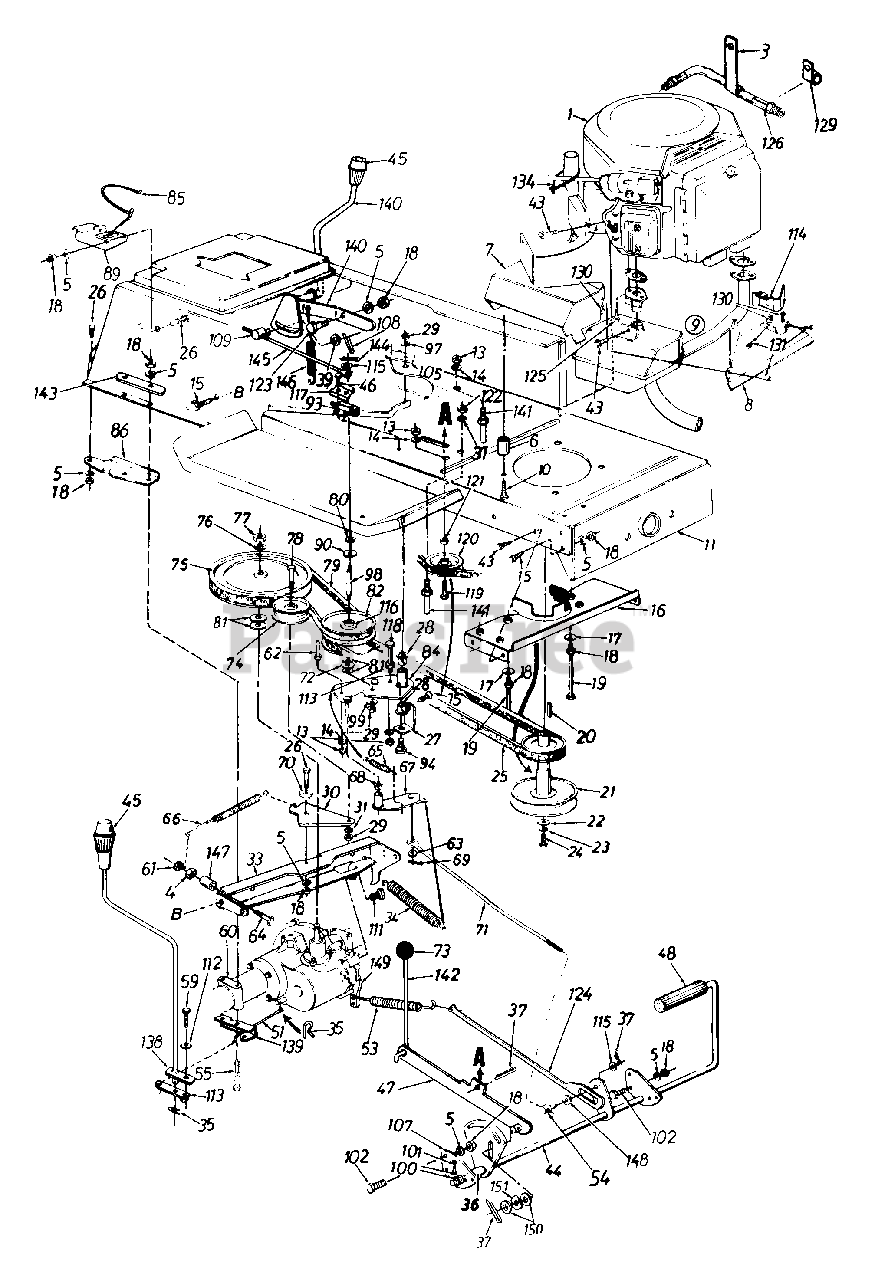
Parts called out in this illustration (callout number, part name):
1	Engine
4	Hex Nut 5/16-24 Thd.
5	L-Wash. 5/16" I.D.
6	Spacer 1.25" Lg.
7	Muffler Heat Shield
8	Front Heat Shield
9	Muffler Ass'y. Comp.
10	Hex L-Wash. Tap Scr. 3/8-16 Thd.
11	Lower Frame Ass'y.
13	Hex Nut 1/4-20 Thd.
14	L-Wash. 1/4" I.D.
15	Hex Wash. TT-Tap Scr. 5/16-18 x .62" Lg.
16	Belt Guard Brkt. Ass'y.
17	Bell-Wash. .345" I.D. x .88"
18	Hex Nut 5/16-18 Thd.
19	Hex Bolt 5/16-18 x 4.0"
20	Sq. Key 1/4" x 1/4" x 2.00"
21	Engine Pulley
22	Fl-Wash. 7/16" I.D. x 1.25"
23	L-Wash. 7/16" I.D.
24	Hex Bolt 7/16-20 x 1.50" Lg.
25	Variable-Speed Belt
26	Hex Bolt 5/16-18 x .75" Lg.
27	Bearing Shaft Bracket Ass'y.
28	Flanged Nyliner Brg. .63" I.D. x .6" Lg.
29	Hex Nut 3/8-24 Thd.
30	Idler Bracket
31	L-Wash. 3/8" I.D.
33	Transaxle Support Brkt.
34	Ext. Spring .94" O.D. x 7.58"
35	Inter. Cotter Pin
36	Spacer .63" I.D.
37	Cotter Pin 1/8" Dia. x 1.0" Lg.
39	FL-Wash. .51" I.D. x .75"
43	Hex Wash. Hd. S-Tap Scr. 1/4-20 x .50" Lg.
44	Clutch/Brake Pedal Ass'y.
46	Truss Mach. B-Tap Scr. #10 x .5" Lg.
47	Parking Brake Lockout Brkt. Ass'y.
48	Foot Pad
51	Shift Lever Rod
53	Ext. Spring 3.6"
54	Ferrule
55	Hex Bolt 5/16-18 x 3.25"
59	Hex Bolt 1/4-28 x .62" Lg.
60	Transaxle Complete
61	Hex L-Nut 1/4-20 Thd.
62	Belt Guard Pin 1/4-20 Thd.
63	Fl-Wash. .34" I.D. x .68" O.D.
64	Hex Wash. TT-Tap Scr. 1/4-20 x 1.75"
65	Ext. Spring 2.59" Lg.
66	Ext. Spring .5" O.D. x 4.35"
68	Flanged Bearing
69	Cotter Pin 3/32" Dia.
70	Shoulder Spacer .27" Lg.
71	Speed Control Link
72	Truss Bearing .56 Dia. x 1.25"
74	Fl-Idler Pulley 3.25" x .75"
76	L-Wash. 1/2" I.D.
77	Hex Jam Nut 1/2-20 Thd.
78	Hex Bolt 3/8-24 x 1.75" Lg.
79	Variable Speed Belt
80	Snap Ring .56" Dia.
81	Fl-Wash. .56" I.D. x 1.0" O.D.
82	Variable Speed Pulley Ass'y. 5" O.D.
90	Teflon Washer .565" I.D.
93	Safety Switch (Clutch)
94	Shld. Bolt 3/8-24 x 3.12" Lg.
97	Bell-Wash. .38" I.D. x .88"
99	Bell-Wash. .39" I.D. x 1.12"
100	Fl-Wash. .64" I.D. x .94"
101	Cotter Pin 1/8" Dia. x 1.25" Lg.
102	Hex Wash. Hd. Scr. 5/16-18 x .62" Lg.
109	Ferrule
111	Hex Wash. Tap Scr.
112	Bell-Wash. .265" I.D. x .75"
113	Shift Lever Link Ass'y.
114	Front Heat Shield Ext.
115	Fl-Wash. .385" I.D. x .62"
116	Needle Brgs.
117	Switch Plate
118	Hex Bolt 1/4-20 x 3.5" Lg.
119	Hex Bolt 3/8-16 x 1.25" Lg.
120	Fl-Idler w/Flanges 2.75" O.D.
121	Fl-Wash. .39" I.D. x 1.12" O.D.
122	Hex Nut 3/8-16 Thd.
123	Shld. Bolt .437" Dia. x .162"
124	Brake Rod Ass'y.
125	Hex Bolt w/Washer
129	Clamp
130	Speed Nut #10-24 Thd.
131	Hex B-Tap Scr. #10 x .38" Lg.
134	Cable Tie
138	Shift Lever Ass'y.
139	Shift Lever Support Brkt.
140	Speed Selector Lever Ass'y.
141	Belt Guard Pin
142	Brake Lockout Rod
144	Cotter Pin 1/8" x 3/4" Lg.
145	Speed Selector Rod
146	Ext. Spring 3.97" Lg.
147	Spacer .326" I.D. x .47"
148	Fl-Wash. 5/8" I.D. x 1.25"
149	Actuating Arm
150	Fl-Wash. .385" I.D. x .87" O.D.
151	Wave Wash. .38" I.D. x .75"
